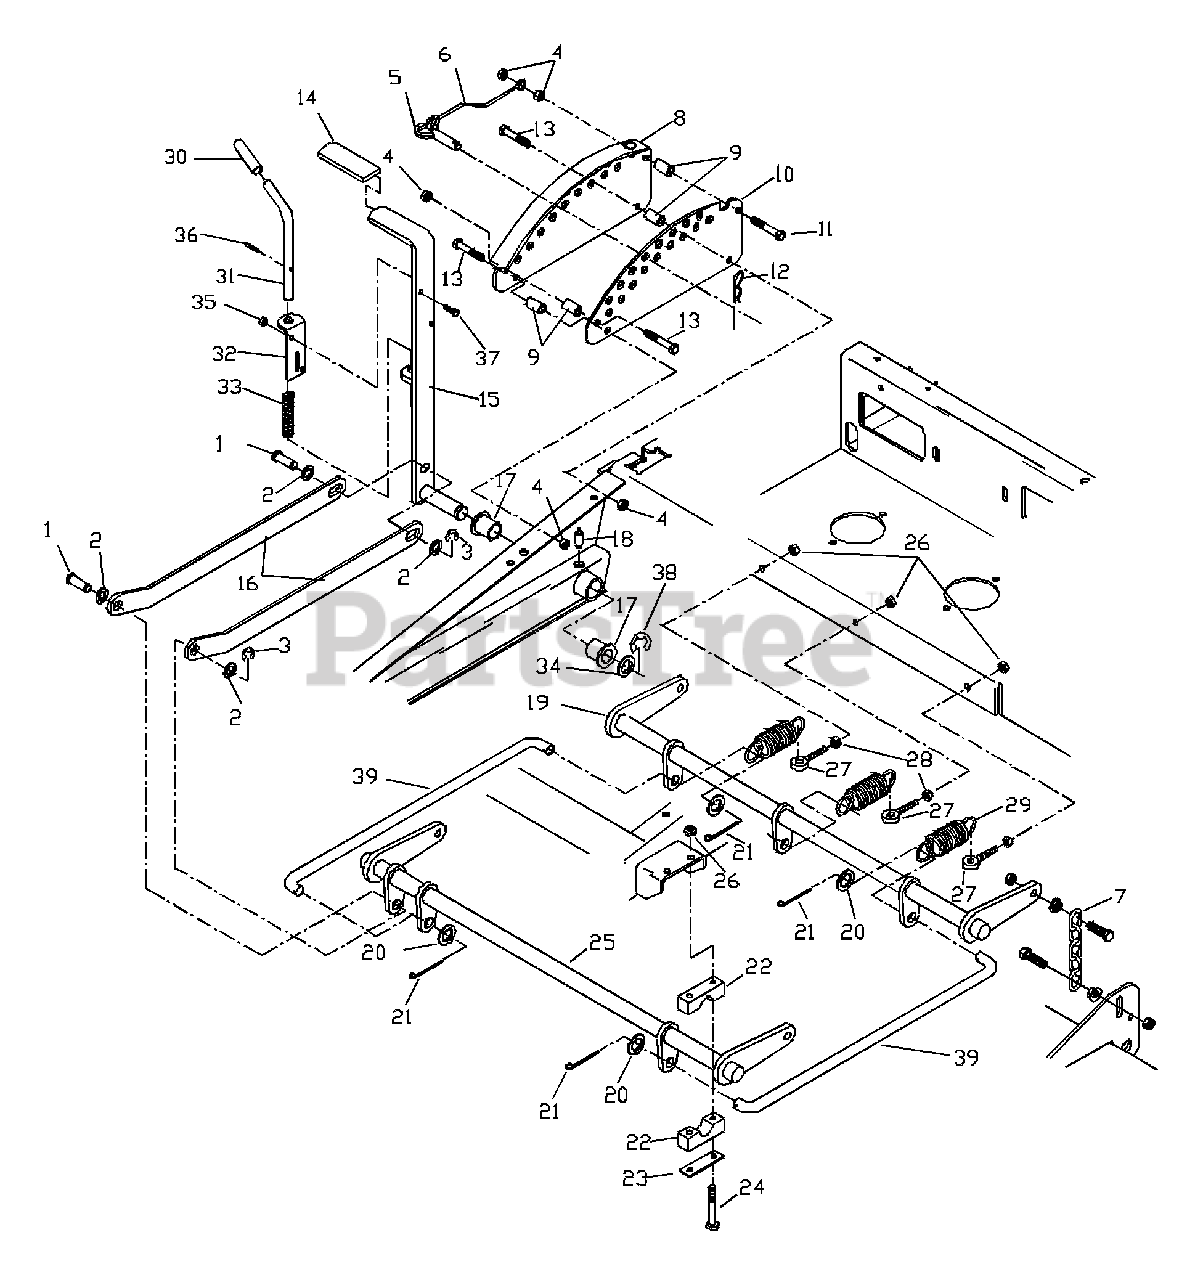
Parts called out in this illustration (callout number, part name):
1	CLEVIS PIN
2	MACH. BUSHING
3	5/8 E - RING
4	NUT 3/8C CTR. LOCK
7	LIFT CHAIN
8	ADJ. PLATE WLDMT.
9	DECK LIFT SPACER
10	ADJ. PLATE PAINTED
11	HCS 3/8C X 2.5
12	# 4 HAIR PIN
13	HCS 3/8C X 2.25
15	LEVER WLDMT.
16	LIFT LINKAGE
17	FLANGE BUSHING
18	ZERK - LONG
19	LIFT SHAFT
20	5/8 SAE WASHER
21	COTTER PIN
22	PILLOW BLOCK
23	SUPPORT PLATE
24	HCS 5/16C X 2.5
25	LIFT SHAFT, FRONT
26	NUT 5/16C CTR. LOCK
28	5/16C WHIZ NUT
29	DECK LIFT SPRING
32	PIN MT.,UPPER
34	MACH. BUSHING
35	NUT 1/4C CTR. LOCK
36	3/16 X 1 ROLL PIN
37	HCS 1/4C X 3/4
38	7/8 E - RING
39	CONN. LINK
